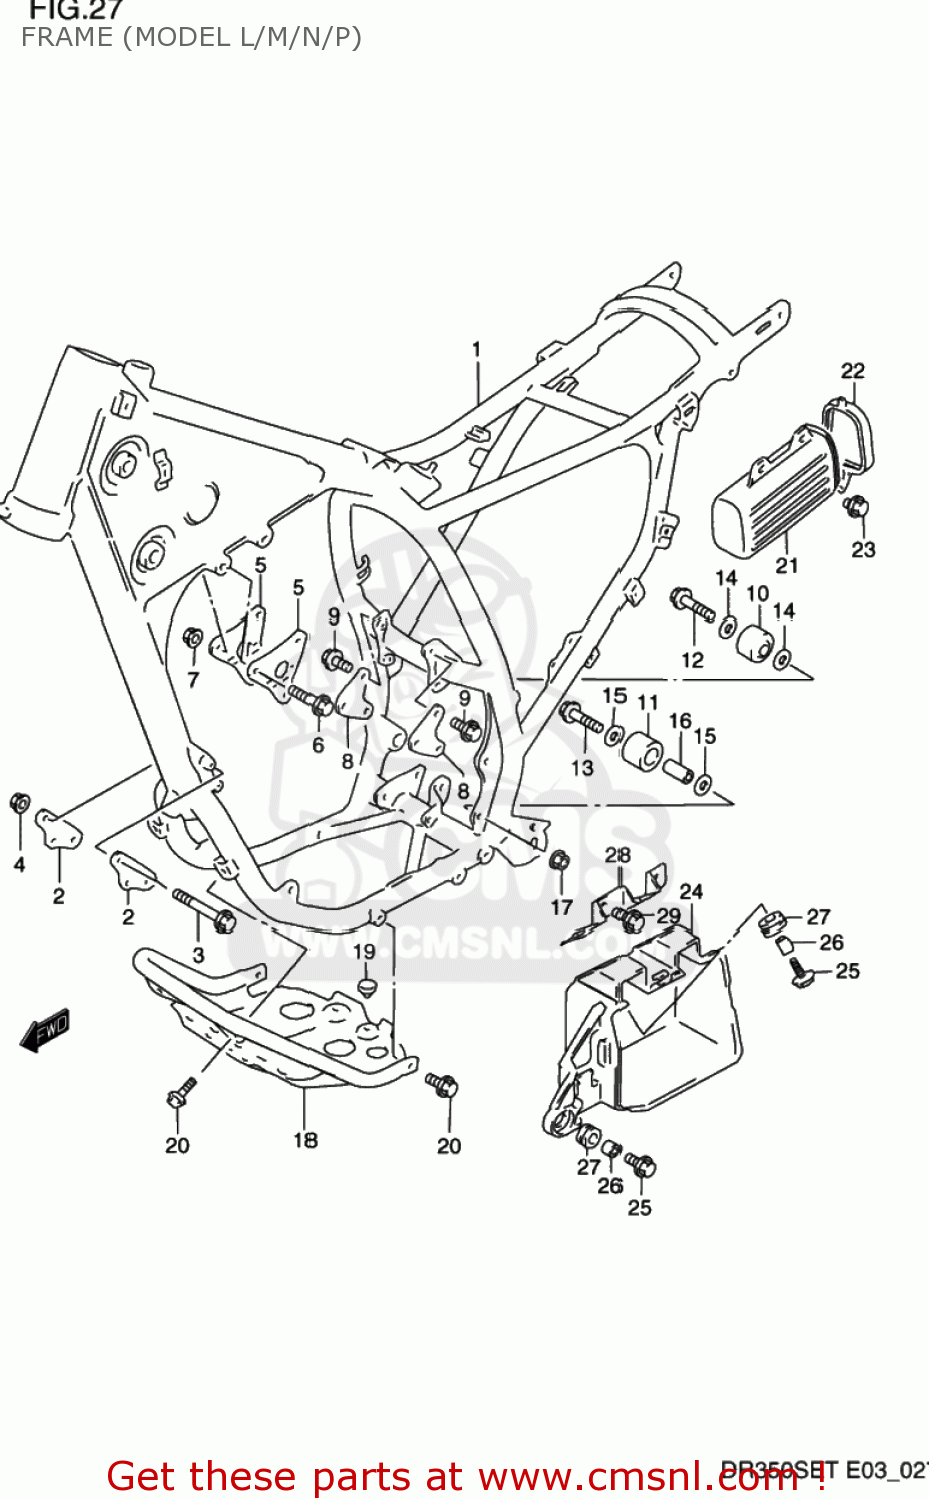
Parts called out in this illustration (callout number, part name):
1	FRAME
2	PLATE,ENGINE MOUNT FR
3	BOLT(8X85)
4	NUT
5	PLATE,ENGINE MOUNT UPR
6	BOLT(8X70)
7	NUT
8	PLATE,ENGINE MOUNTING,REAR
9	BOLT(8X16)
10	ROLLER,CHAIN
11	ROLLER,CHAIN CONTROL
12	BOLT(8X38)
13	BOLT
14	WASHER
15	WASHER
16	SPACER (8.6X13.8X28)
17	NUT
18	PROTECTOR,ENGINE
19	CUSHION
20	BOLT
21	HOLDER,TOOL
22	CAP,TOOL HOLDER
23	BOLT M6X16
24	HOLDER,BATTERY
25	BOLT(6X20)
26	SPACER
27	CUSHION
28	PLATE COMP,BATTERY HOLDER
29	BOLT
